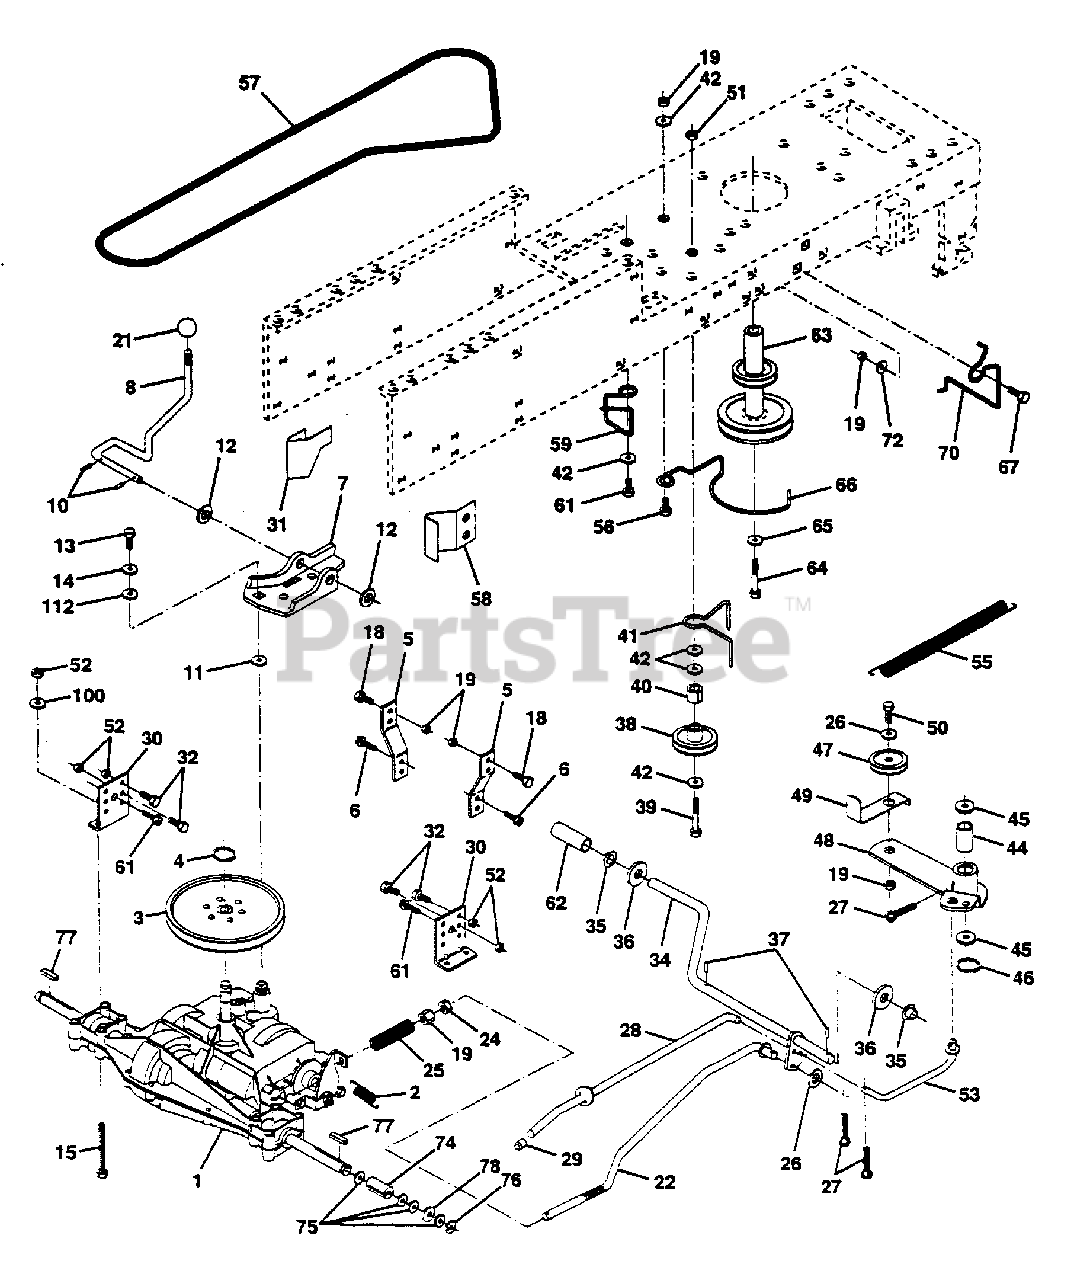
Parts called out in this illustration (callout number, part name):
2	SPRING.BRAKE.RETU
3	PULLEY TRANS
5	STRAP TORQUE
6	SCREW
8	SHIFT ROD
10	PIN COTTER 1/8
11	WASH-SHFT PLT LT
12	WASHER
13	BOLT.1/4-28.W/PAT
14	LOCKWASHER
15	BOLT HEX
18	BOLT
19	NUT
21	KNOB T (1/2-HOLE)
22	BRAKE ROD
24	NUT
25	SPRING ROD LT
26	WASHER
27	COTTER PIN
28	ROD.BRAKE.PARK.LT
29	PLUNGER CAP T
30	TRANSAXLE MTG BKT
31	"KEEPER,BELT LH T"
32	BOLT
34	SHAFT.PEDAL.FOOT
35	NYLON BEARING
36	WASHER LT
38	PULLEY.IDLER.FLAT
39	BOLT
40	SPACER T
41	BELT KEEPER LT
42	WASHER
44	"LY, BEARING"
45	WASHER LT
46	KLIP RING
48	ARM IDLER
49	RETAIN BELT
53	"LINK, CLUTCH T"
55	"SPRING, RETURN LT"
58	"KEEPER,BELT RH T"
59	KEEPER BELT CNTSP
61	SCREW
62	PEDAL COVER T
63	PULLEY.ENGINE
64	BOLT
65	LOCKWASHER
66	KEEPER.BELT.ENG.L
67	BOLT
70	KEEPER BELT ENG
72	WASHER
74	SPACER LT
75	WASHER
76	E-RING LT
77	SQUARE KEY
78	WASHER
100	WASHER M
112	WASHER LT
